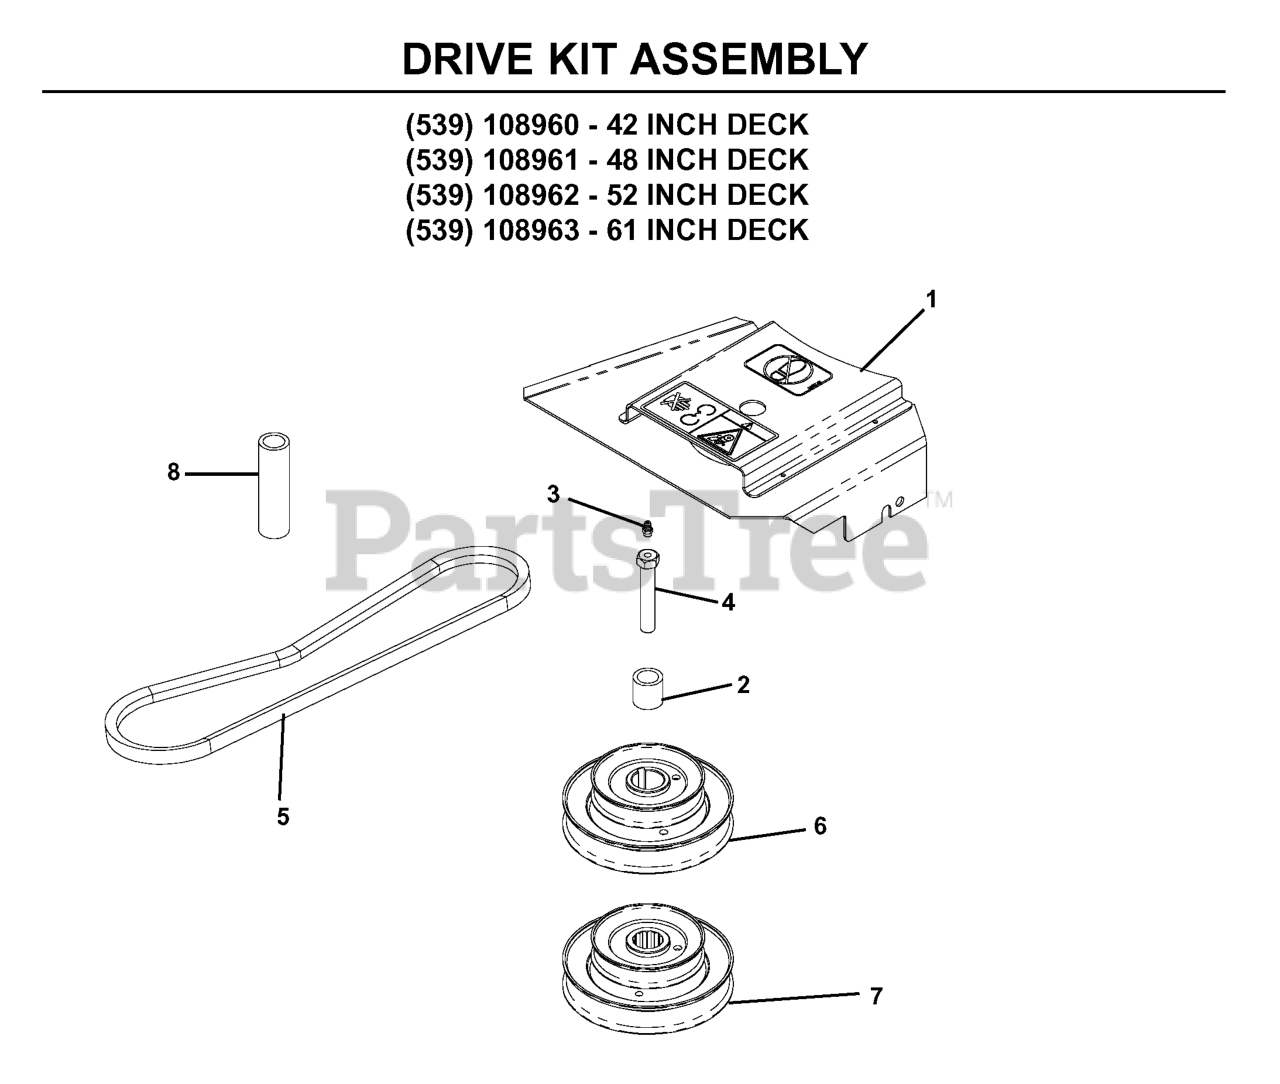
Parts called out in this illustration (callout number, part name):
1	SHEILD WELDMENT 42
2	SPACER
3	ZERK
4	DRILLED BOLT 7/16-20 X 2 1/2"
5	V-BELT 42" SPINDLE DRIVE
6	STACKED SHEAVE 42-48
